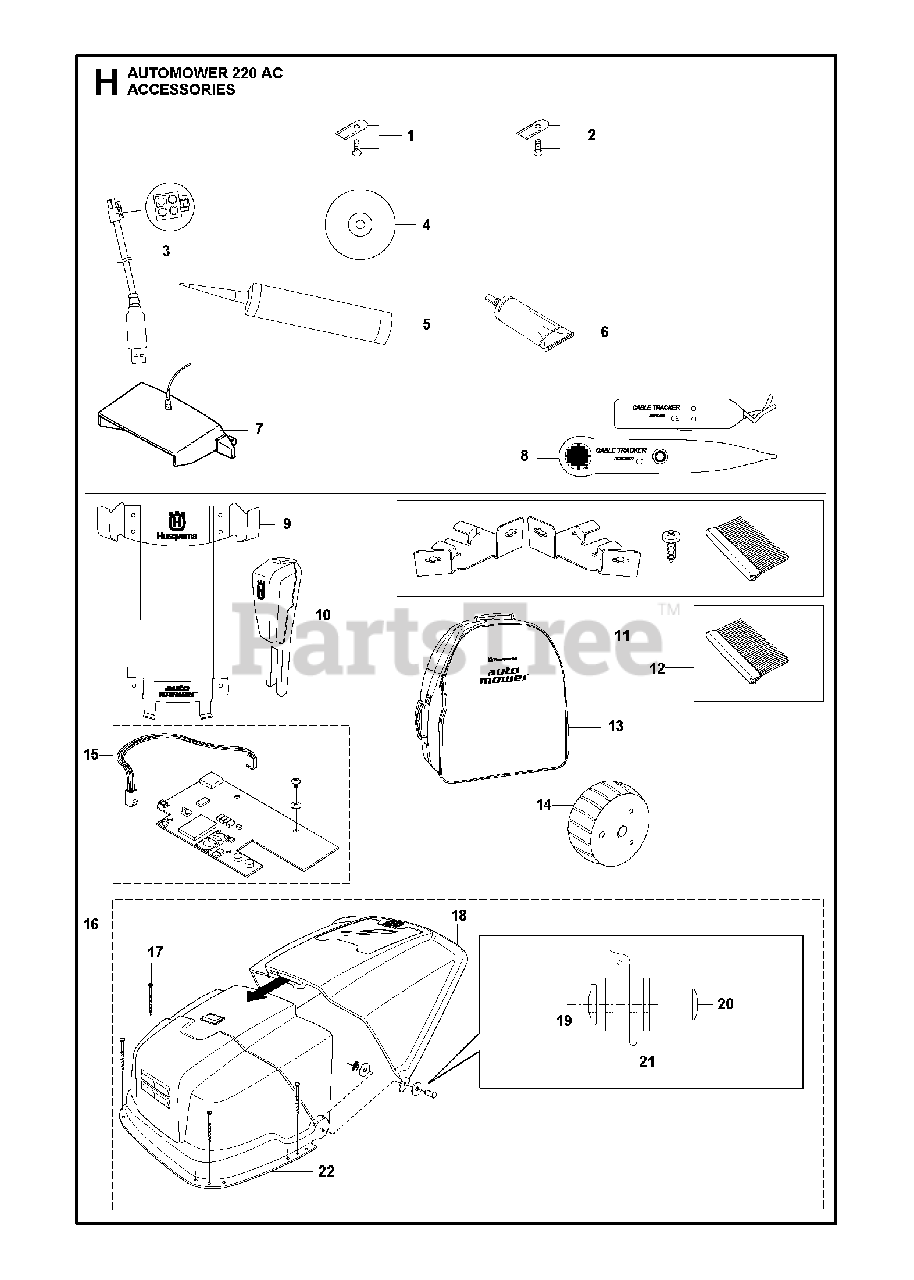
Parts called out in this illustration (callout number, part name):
1	BLADE
1	BLADE KIT
1	BLADE - 30 PCS
1	BLADE - BULK PACK 500 PCS
2	BLADE 9PCS EXTRA THICK
2	Blade Set, 9 Piece Extra Thick
2	BLADE CARBON STEEL, THICK BLAD
2	BLADE 300PCS -SINGLE HOLE THIC
3	USB SERVICE CABLE
5	GREASE 300 ML
6	SEALANT
6	GREASE OKS 110 85ML
7	N/A PIN CODE TRANSFER UNIT ADA
8	TEST EQUIPMENT
9	WALL BRACKET ASSY
10	SIGNAL BOOSTER
11	BRUSH KIT
11	BRUSH KIT BRUSH X6, HOLDER X2,
12	BRUSH KIT
14	WHEEL ASSY
14	HEAVY FRONT WHEEL KIT
15	GPS UNIT
16	AUTOMOWER SHELTER
17	SCREW KIT CS
18	TOP INCL LOGO & WINDOW CHARG
19	LOCK WASHER
20	AXLE CHARGING STATION COVER
21	WASHER
22	FRONT CHARGING STATION COVER
